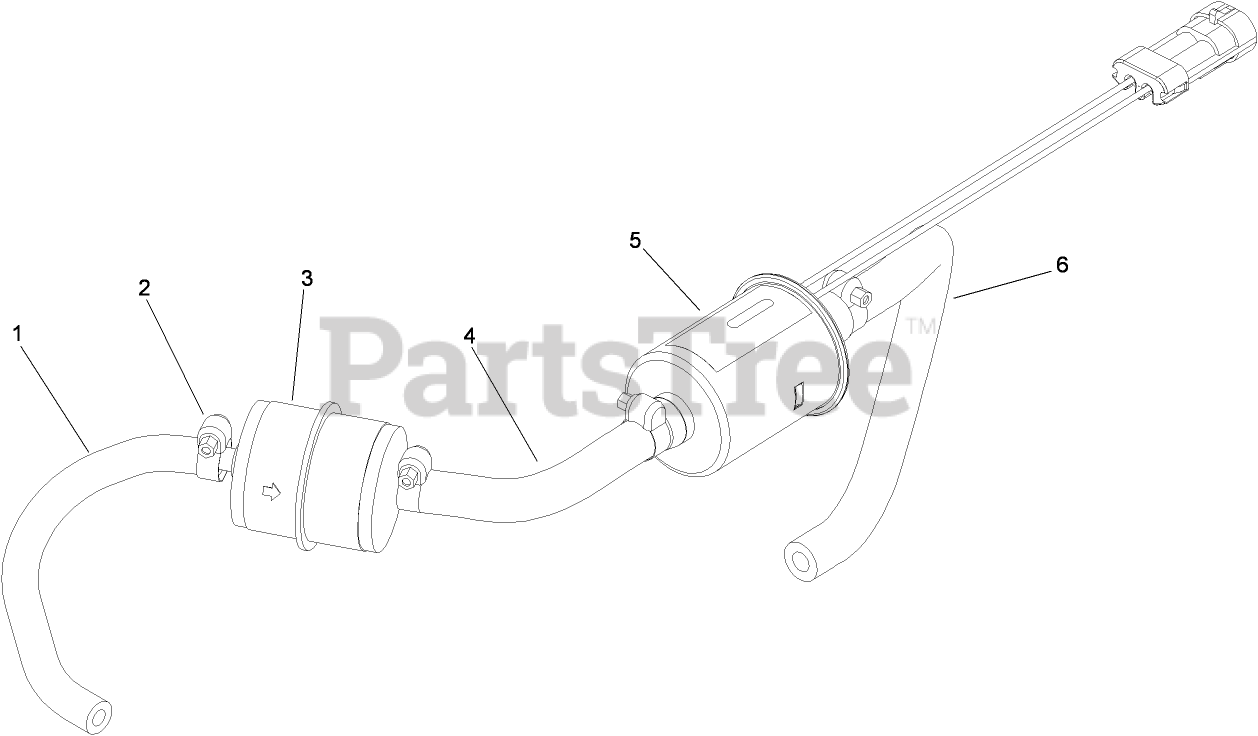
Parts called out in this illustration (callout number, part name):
1	HOSE-FUEL
2	CLAMP-WORM
3	FILTER-INLINE
4	HOSE-FUEL
5	PUMP-FUEL
6	HOSE-FUEL
